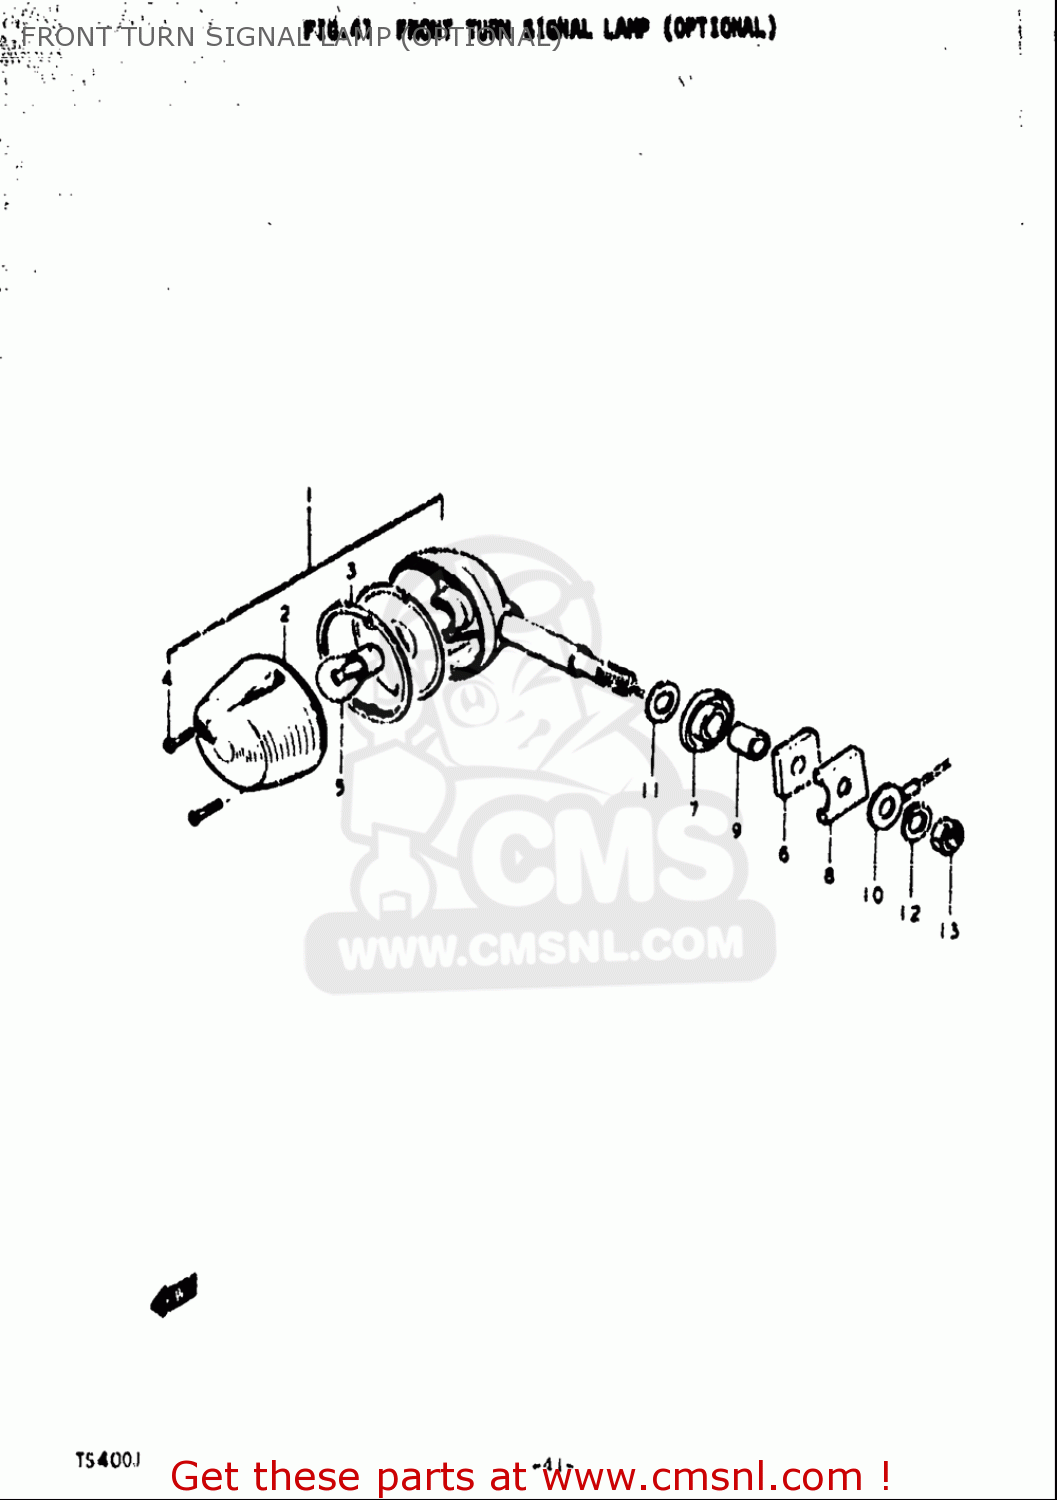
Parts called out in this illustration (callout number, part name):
2	LENS,TURNSIGNAL
3	GASKET,TURNSIGNAL LENS (NAS)
4	SCREW
5	BULB(12V23W,STANLEY,A4577A)
12	WASHER,LOCK
13	NUT
